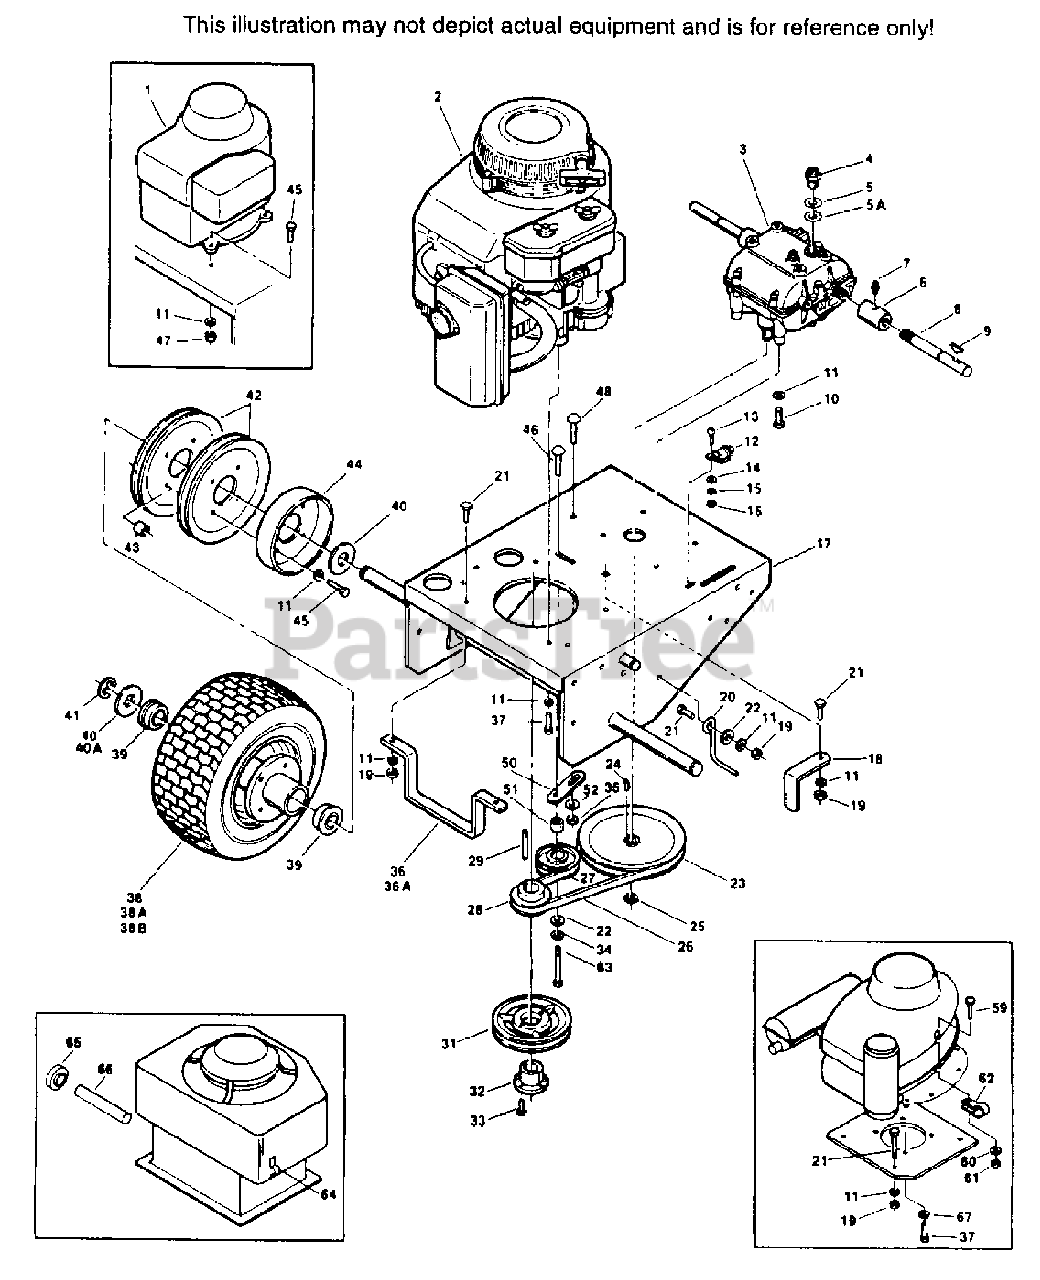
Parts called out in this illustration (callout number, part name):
3	TRANSMISSION(PEERLESS 700-022)
4	NEUTRAL SAFETY SWITCH
5	FIBRE WASHER, THIN
5A	FIBRE WASHER, THICK
6	COUPLER, JACKSHAFT
7	GREASE FITTING, STR. 1/4-28
8	JACKSHAFT
9	KEY, HI-PRO #9
12	CLUTCH SAFETY SWITCH(BLACK HOUSING)
15	LOCKWASHER, #10 EXT. TOOTH
18	REAR BELT GUIDE, ENGINE
20	BELT GUIDE, TRACTION DR.
21A	CARRIAGE HD BOLT 5/16-18 X 1
22	WASHER, 25/64 X 15/16 X 12 GA.
23	PULLEY, TRANS. INPUT
24	KEY, WOODRUFF #9
25	RETAINING RING, 5/8 EXT.BASIC
26	BELT, TRANSMISSION DRIVE
27	IDLER PULLEY, TRANSMISSION
28	PULLEY, TRACTION DRIVE
29	KEY, 1/4 X 1/4 X 2-1/2
31	PULLEY, BELT DR.(INCL. 32-33)
32	TAPER HUB(FOR 48127)
39	WHEEL BEARING
40	WASHER, 1-1/16 X 1-3/4 X 12 GA.
40A	WASHER, 1-1/16 X 1-1/2 X 18 GA.
41	RETAINING RING, 1" EXT.-"E"
42	PULLEY, WHEEL DRIVE
43	SPACER, WHEEL PULLEY
44	BRAKE DRUM
46	SH.SQ.NK.CAR. BOLT, 3/8-16 X 2
47	HEX NUT, 5/16-18 ELASTIC STOP
